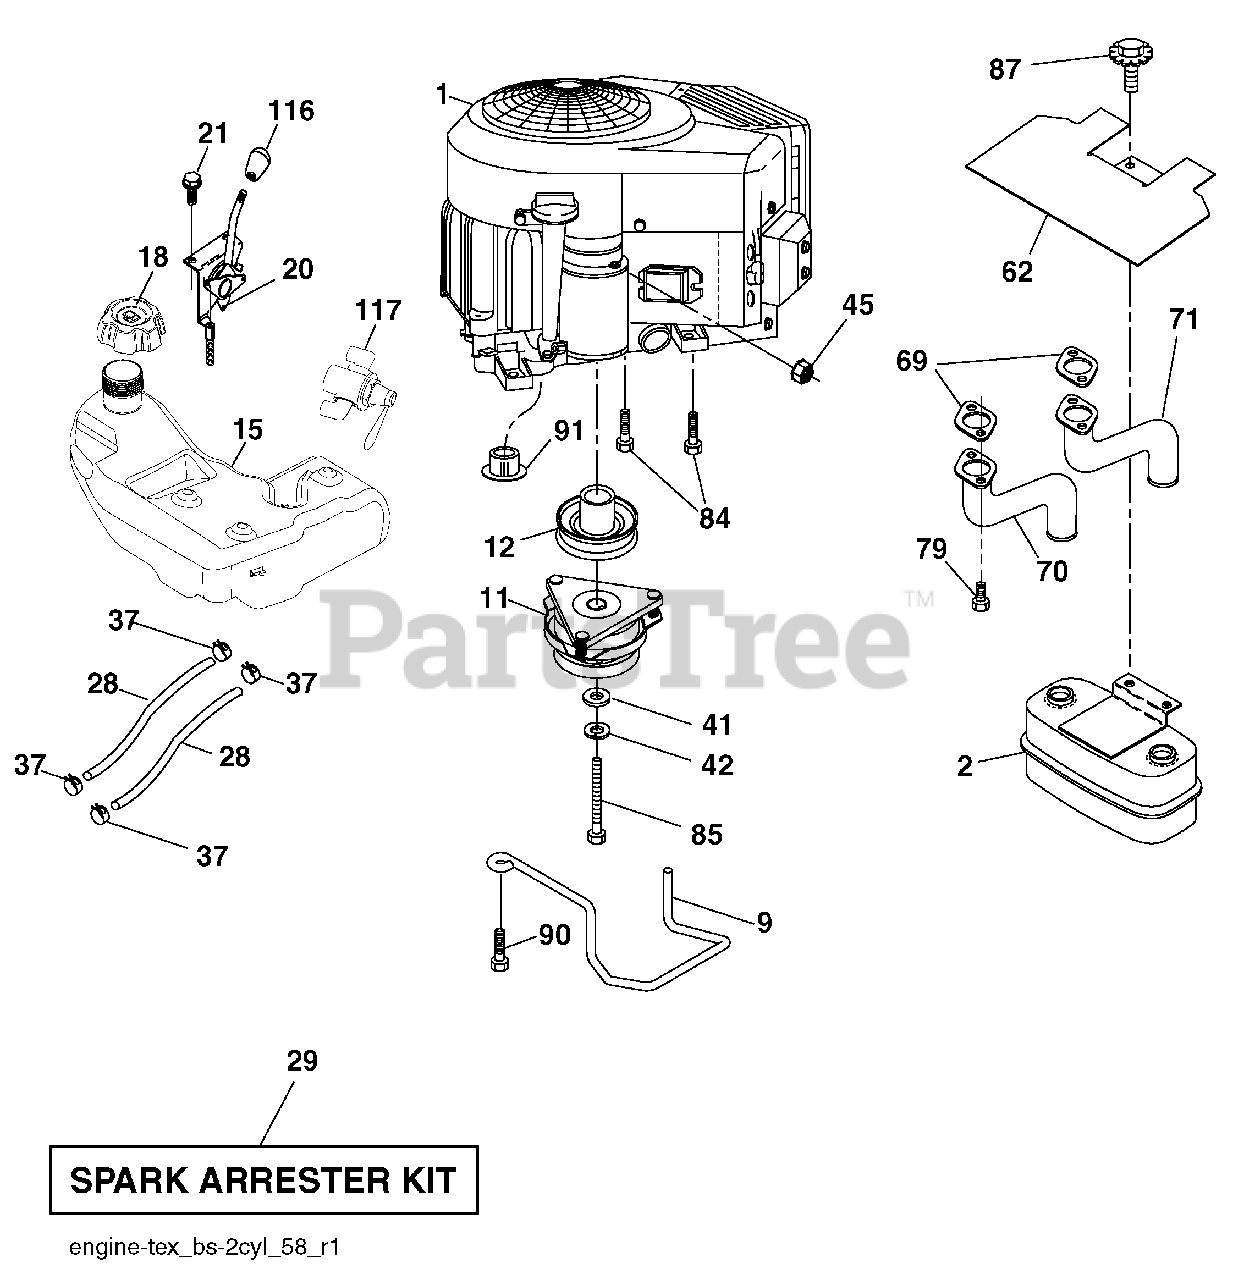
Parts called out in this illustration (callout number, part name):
9	Keeper Belt Engine
11	Clutch
12	Pulley Engine
18	Cap Asm
20	Control Throttle
21	Screw #10 x .750 BOS Thread
28	Fuel Line
29	Spark Arrester Kit
37	Clamp Hose
41	Washer 1-1/2 OD x 15/32 ID x .250
42	Washer Lock 7/16
45	Nut Keps Hex 1/4-20 unc
62	Heat Shield
70	Tube Exhaust LH
71	Exhaust Tube RH
79	Screw Socket HD 5/16-18 x 1
84	Screw 3/8-16 x 1-1/4
85	Bolt Hex 7/16-20 x 4 x Gr. 5-1.5 Thr
87	Bolt 5/16-18 UNC x 3/4 w/Sems
90	Screw 3/8-16 x 1
116	Knob Soft Touch
117	Valve Fuel Reserve
